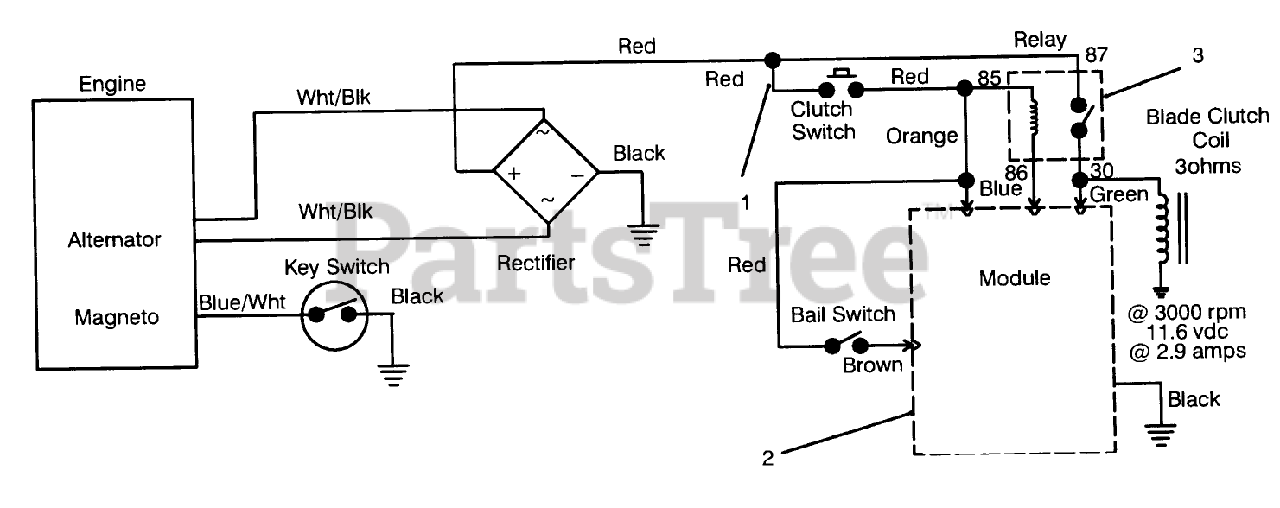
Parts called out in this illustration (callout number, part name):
1	Wire Harness
2	Module
3	RELAY
